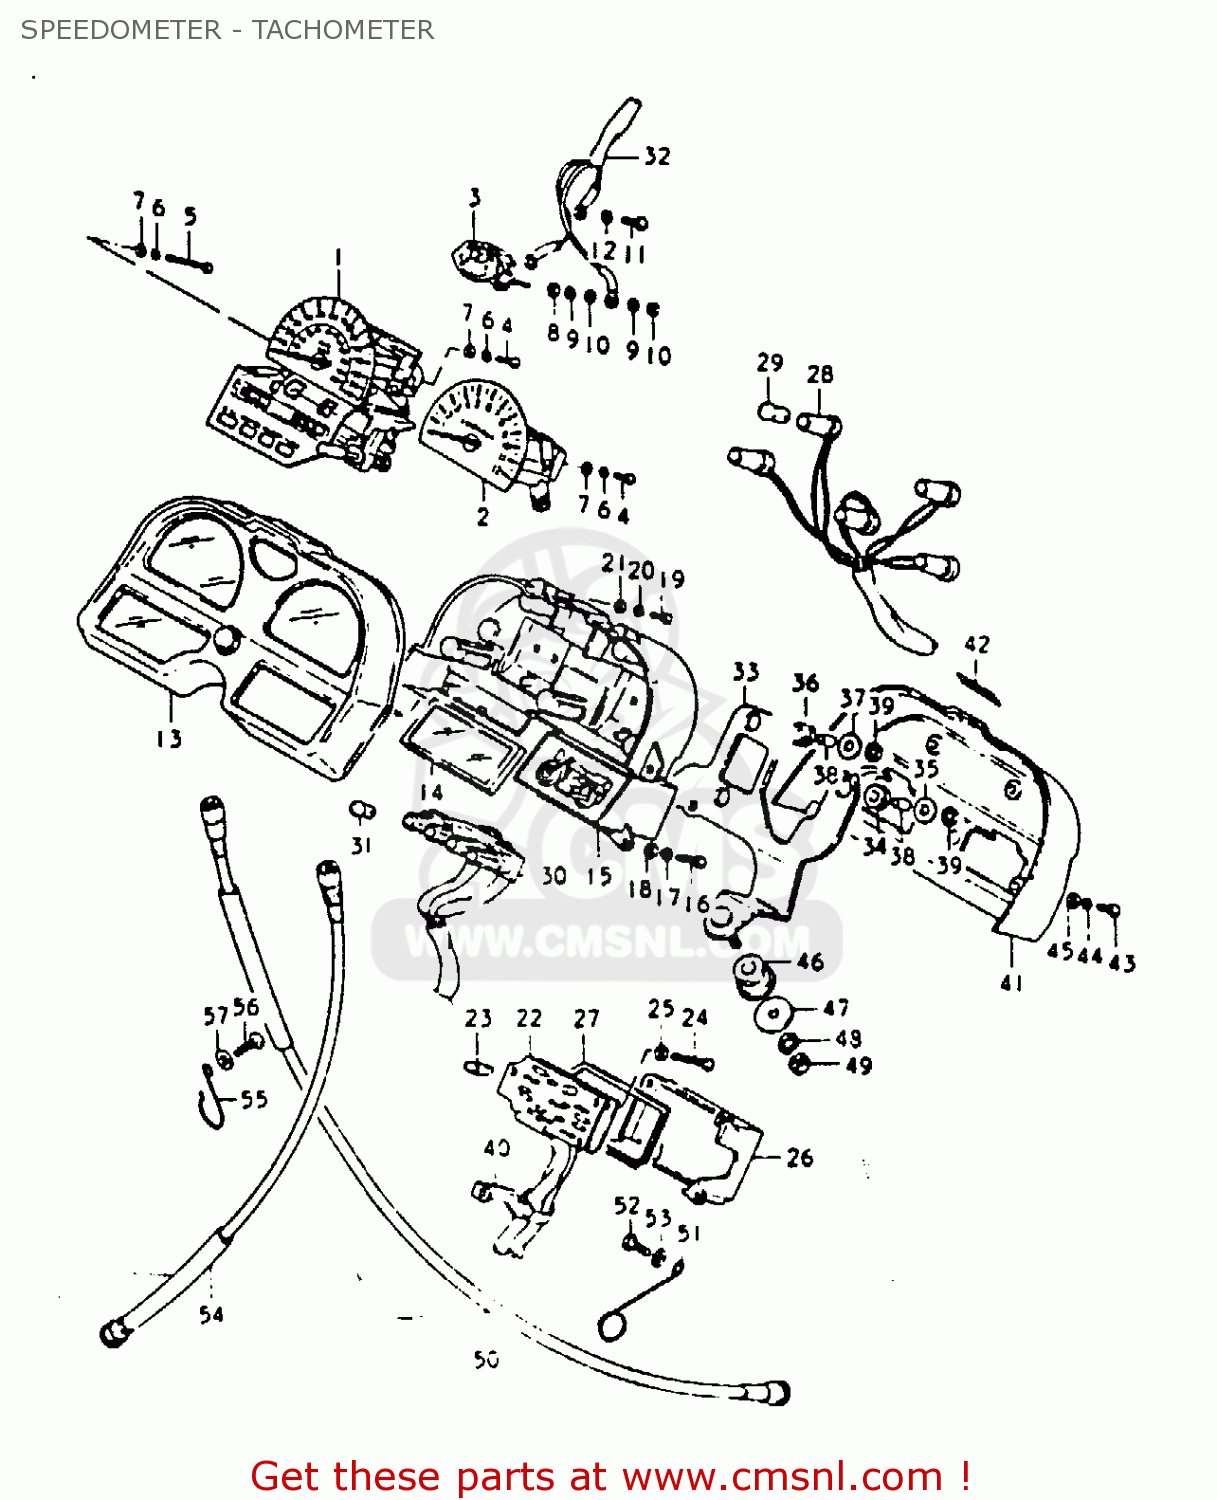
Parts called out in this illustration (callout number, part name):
1	SPEEDOMETER (MILE & KILO)
2	TACHOMETER
3	FUEL METER
4	SCREW
5	SCREW
6	LOCK WASHER
7	WASHER
8	WASHER
9	LOCK WASHER
10	NUT 4MM
11	SCREW
12	LOCK WASHER
13	HOOD, METER
14	GLASS, CHECK PANEL
15	CASE
16	SCREW
17	LOCK WASHER
18	WASHER
19	SCREW 3X12
20	LOCK WASHER
21	WASHER
22	CHECK PANEL UNIT
23	BULB
24	SCREW
25	LOCK WASHER
26	LOWER CASE, CHECK PANEL
27	GASKET
28	SOCKET, METER
29	BULB(12V3.4W,STANLEY,A72A)
30	SOCKET, PILOT LAMP
31	BULB(12V3.4W,STANLEY,A72A)
32	LEAD WIRE, FUEL METER
33	BRACKET
34	CUSHION
35	WASHER,METER
36	CUSHION (B)
37	WASHER (B)
38	SPACER
39	NUT
40	CLAMP
41	COVER, LOWER
42	EMBLEM
43	SCREW
44	LOCK WASHER
45	WASHER
46	CUSHION,METER
47	WASHER (8.5X29X1.6)
48	LOCK WASHER
49	NUT
50	CABLE ASSEMBLY,SPEEDOMETER
51	GUIDE,SPEEDOMETER CABLE
52	BOLT, UPPER
53	WASHER
54	CABLE ASSEMBLY,TACHOMETER
55	GUIDE,WIRING HARNESS
56	SCREW 6X12
57	WASHER
